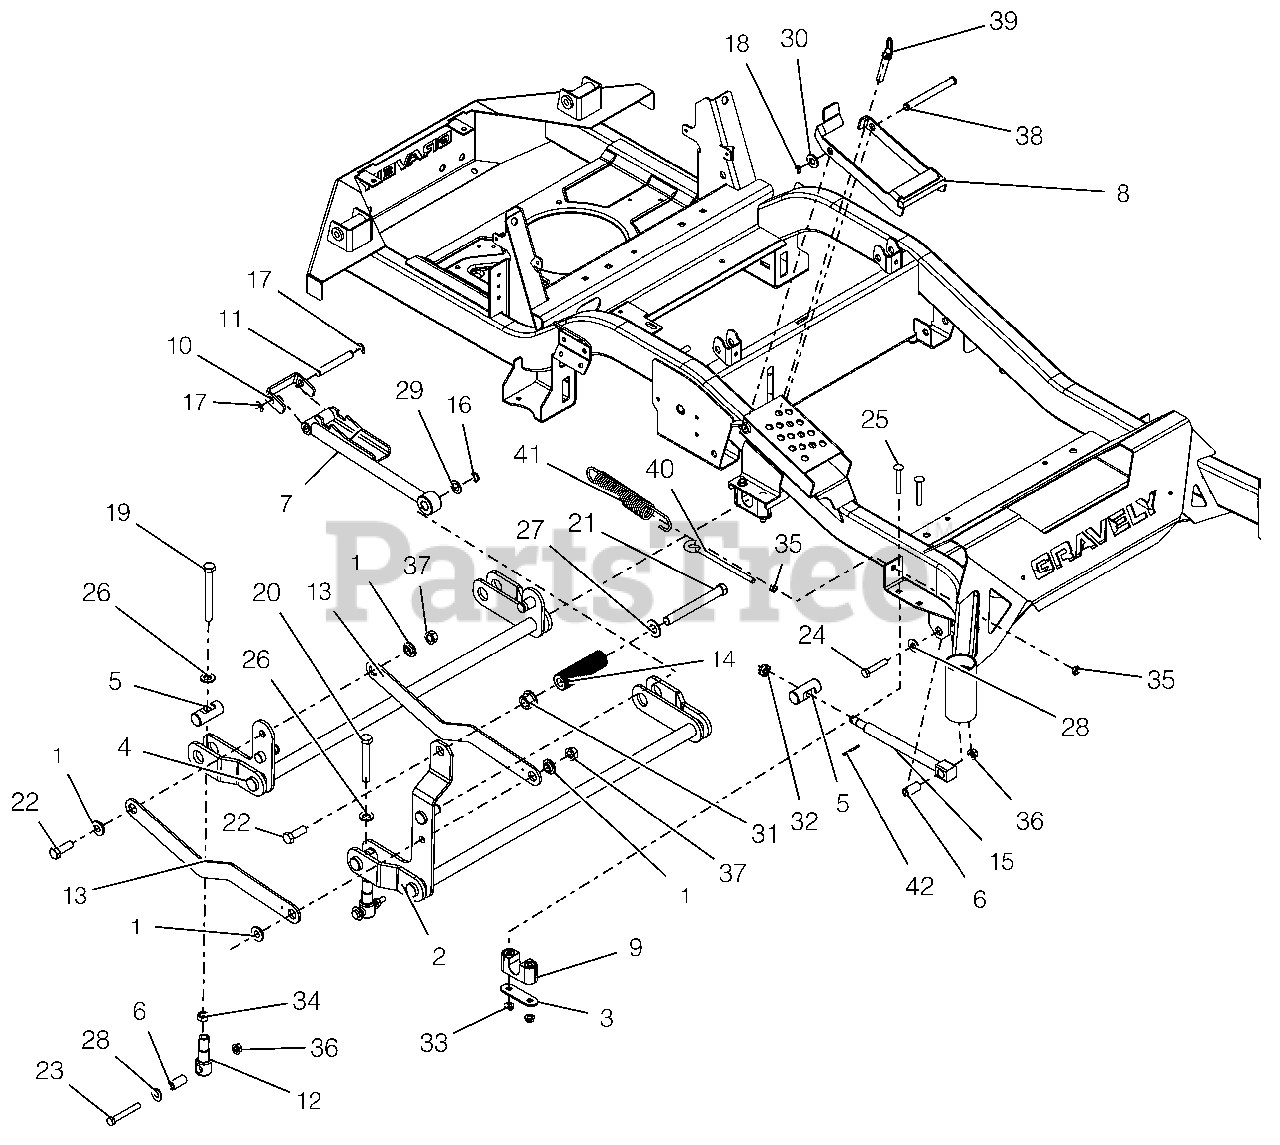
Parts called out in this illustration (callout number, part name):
1	BSHG-FLG .515X.750X.310X1.120
2	WLDMT, FRONT DECK LIFT PIVOT
3	PLATE, BEARING SUPPORT
4	WLDMT, REAR DECK LIFT PIVOT
5	PIN, DECK LIFT
6	SPACER, DECK LEVELING
7	WLDMT, HOC ARM
8	BRKT, HOC TRANSFER LOCK
9	ASM-BUSHING, DECK LIFT
10	BRKT, HOC LINE
11	ROD, HOC PIVOT
12	LINK, DECK LIFT FORMED
13	LINK, DECK LIFT
14	ROD, FOOT PEDAL (BLACK)
15	DRAG,LINK-HD
16	RG-RTNG-EXT .625X.050
17	RG-RTNG-EXT .500X.042 (E)
18	RG-RTNG-EXT .500X.050 (SNAP)
19	@BLT-HEX .5-13-4.5GR8 FULL THD
20	BLT-HEX .50-13X3.50 GR5 FTH
21	BLT, HEX .62-11X5.50 G5 FBP
22	@BLT-HEX .50-13X1.50 GR5 YWZC
23	BLT-HEX .38-16X2.75 GR8 YWZC
24	@BLT-HEX .38-16X2.00 GR5 YWZC
25	BLT-RDHDSQSHNK .31-18X2.25 YWZ
26	FLATWASHER 1/2 SAE HARD 15906
27	WSHRFLT 5/8SAE CARBHARD FBP
28	@WSHR-FL-STL.438X1.00X.083 YWZ
29	WSHR-FL-STL .630X1.005X.062 YZ
30	@WSHR-FL-STL.531X1.06X.095YWZC
31	NUT,FLG-TOP LK .625-11 FBP
32	NUT-SL .50-13
33	@NUT-LK-CTR-FLG .31-18 YZ GR F
34	NUT-JAM .50-13 YWZC
35	NUT-HEX-JAM .375-16 YWZC
36	@NUT-LK-TOP-FLG .38-16 YWZC
37	@NUT-LK-TOP-FLG .50-13 YWZC
38	PIN-CLEV .50X4.75X4.55
39	PIN, .50 X 2.20 USABLE LG BALL
40	BOLT,.38-16 X 5.25-.62 DIA EYE
41	SG-TENS .162X1.25X8.25 WLD 25
42	@PIN-CTR .12X1.25 EXTPRSQCT YZ
